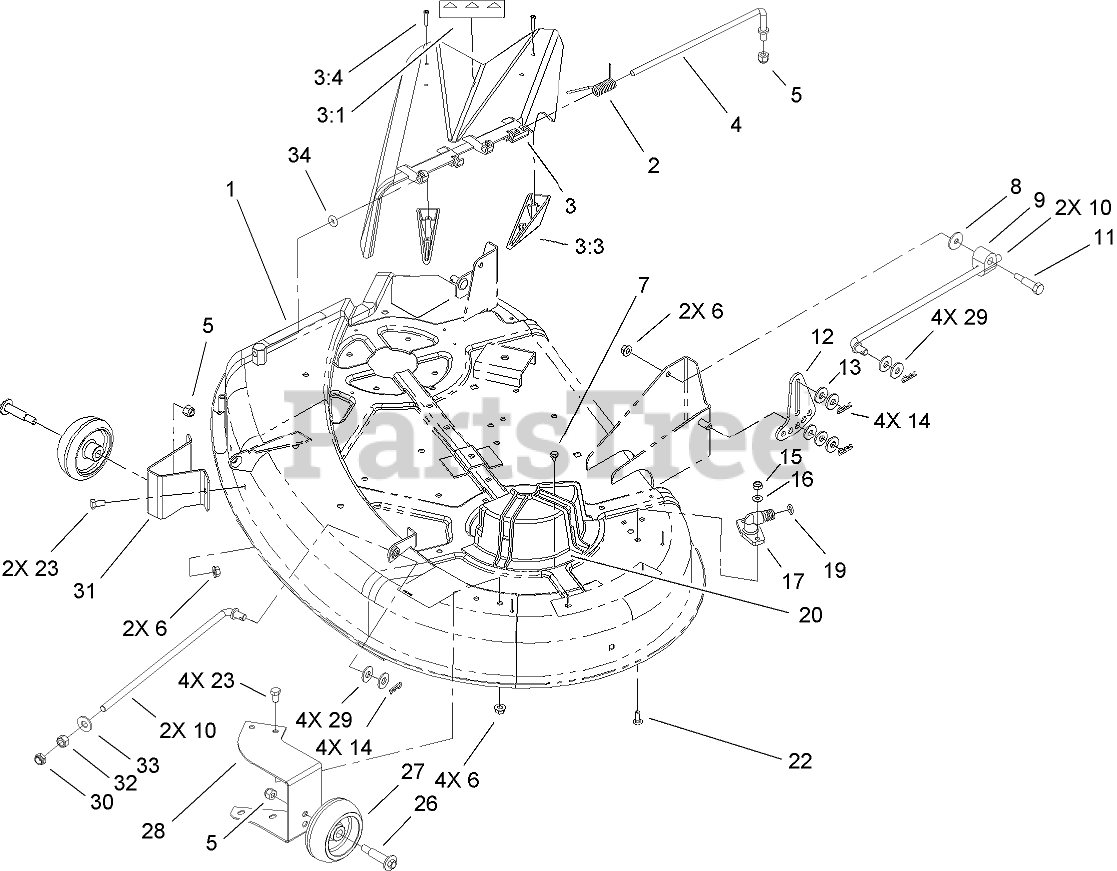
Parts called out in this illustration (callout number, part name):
1	38 INCH DECK ASM
2	SPRING
3	DEFLECTOR ASM
3:1	DECAL-DANGER
3:3	KICKER
3:4	SCREW-PPH
4	ROD-PIVOT
5	NUT-LOCK, NI
6	NUT-HF
7	SCREW-HWHTF
8	WASHER-PIVOT
9	TRUNNION-HOC
10	ROD-HANGER
11	SCREW-SHOULDER, HH
12	LINK-ADJUSTING, HOC
13	WASHER-HARDENED
14	PIN-HAIR
15	NUT-LOCK, NI
16	WASHER-FLAT
17	FITTING-WASHOUT
19	O-RING
20	GUIDE-BELT, LH
22	BOLT-CARR
23	SCREW-HH
26	SCREW-SHOULDER, HWH
27	WHEEL-GAGE
28	BRACKET-WHEEL, GAGE (FRONT, LH)
29	WASHER-FLAT
30	NUT-LOCK, NI
31	BRACKET-WHEEL, GAGE (FRONT, RH)
32	NUT-HEX
33	WASHER-FLAT
34	O-RING
